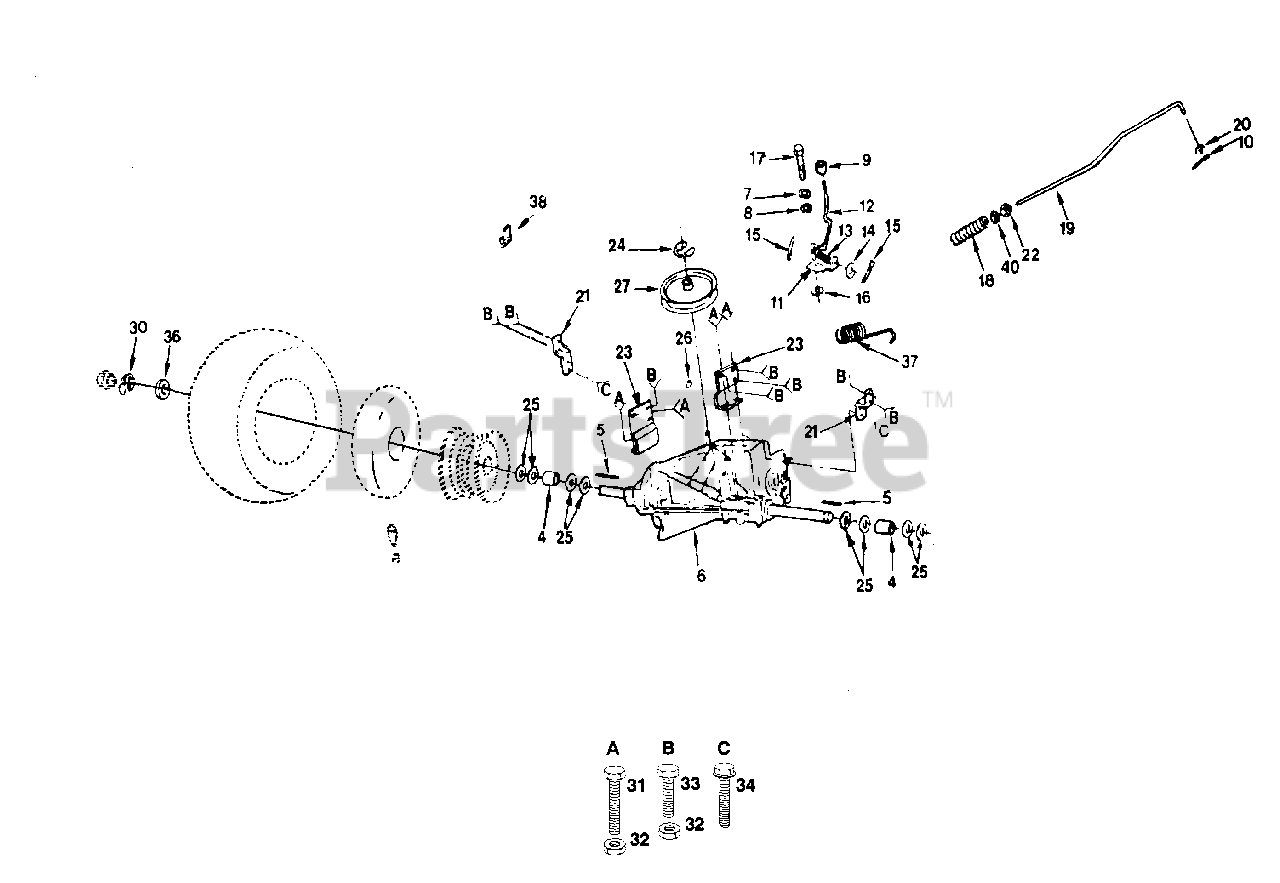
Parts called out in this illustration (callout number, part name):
4	Spacer, Split (AYP part number)
5	Key, Square 3/16 x 2 (AYP part number)
6	Transaxle, Foote, 6 speed (AYP part number)
7	Washer, Lock 1/4 (AYP part number)
8	Washer 9/32 x 3/4 x 10 Ga. (AYP part number)
9	Knob, Control (AYP part number)
10	Pin, Cotter 1/8 x 3/4 (AYP part number)
11	Plate, Rod, Shift (AYP part number)
12	Rod, Shifter (AYP part number)
13	Spring, Torsion (AYP part number)
14	Washer 15/32 x 3/4 x 16 Ga. (AYP part number)
15	Pin, Cotter 1/8 x 1 (AYP part number)
16	Washer, Shift Plate (AYP part number)
17	Bolt, Hex 1/4-28 x 3/4 Grade 8 (AYP part number)
18	Spring, Rod, Brake (AYP part number)
19	Rod, Brake (AYP part number)
20	Washer 13/32 x 13/16 x 16 Ga. (AYP part number)
21	Strap, Torque (AYP part number)
22	Nut, Hex Jam 3/8-16 (AYP part number)
23	Bracket, Transaxle (AYP part number)
24	Ring, Retainer (AYP part number)
25	Washer 25/32 x 1-1/4 x 16 Ga. (AYP part number)
26	Woodruff Key 3/16 x 3/4 (AYP part number)
27	Pulley, Input Transaxle (AYP part number)
30	E-Ring (AYP part number)
31	Bolt, Hex 3/8-16 x 2-3/4 (AYP part number)
32	Locknut 3/8-16
33	Bolt, Hex 3/8-16 x 3/4 (AYP part number)
34	Screw, Hex Washer Hd. Thd. Form. Type TT 5/16-18 UNC x 3/4
36	Washer 25/32 x 1-5/8 x 16 Ga. (AYP part number)
37	Spring, Brake Return (AYP part number)
38	Clip, Line, Fuel (AYP part number)
40	Locknut, Hex w/Washer 3/8-16 UNC (AYP part number)
